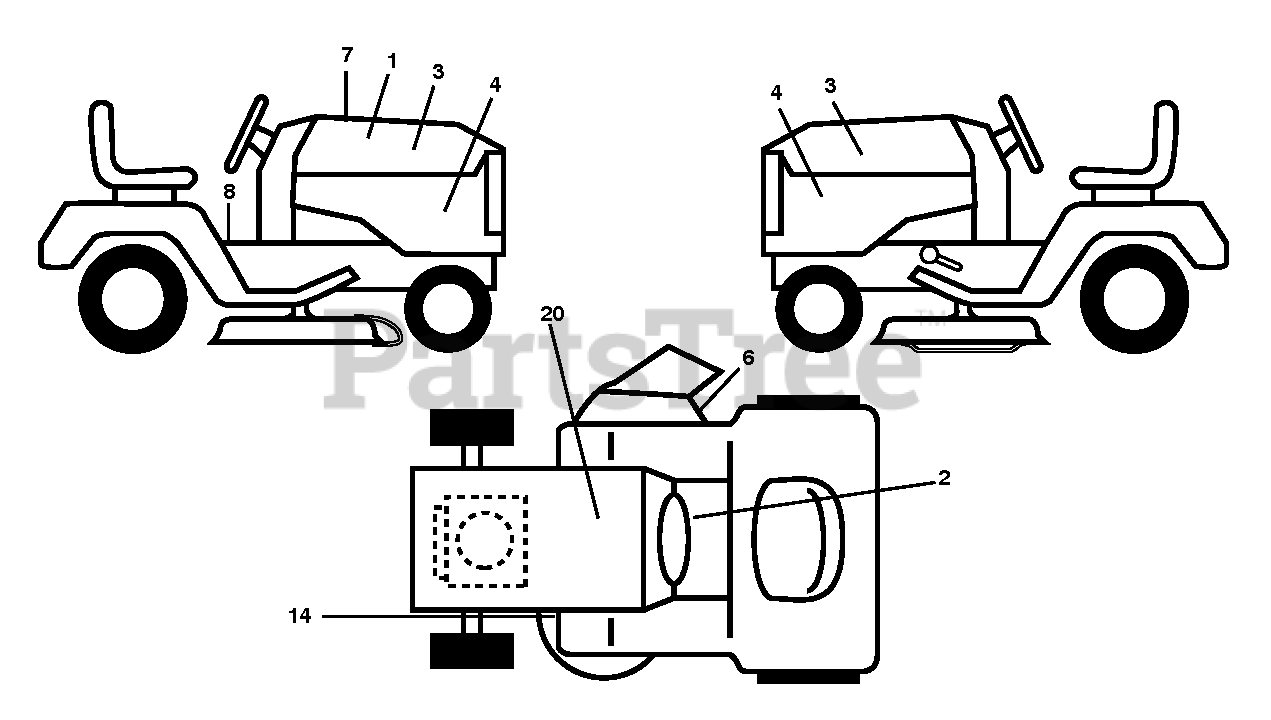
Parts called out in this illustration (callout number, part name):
1	DECAL.WARNING.CUST.RESP.E85.
2	DECAL, WARNING SPARK ARRESTOR
3	DECAL.BADGE.170MM.TEXTLOGO.
4	DECAL.SIDE.PANEL.YTA19K42
6	DECAL.MOWER.WARN.KEEP.HAND.AWY
7	DECAL.REPLACEMENT.YTA19K42
8	DECAL.FENDER.WARNING.ENGLISH
14	DECAL.V-BELT.SCH.42/46"MEC/ELE
20	DECAL BTRY SYMBOLS
